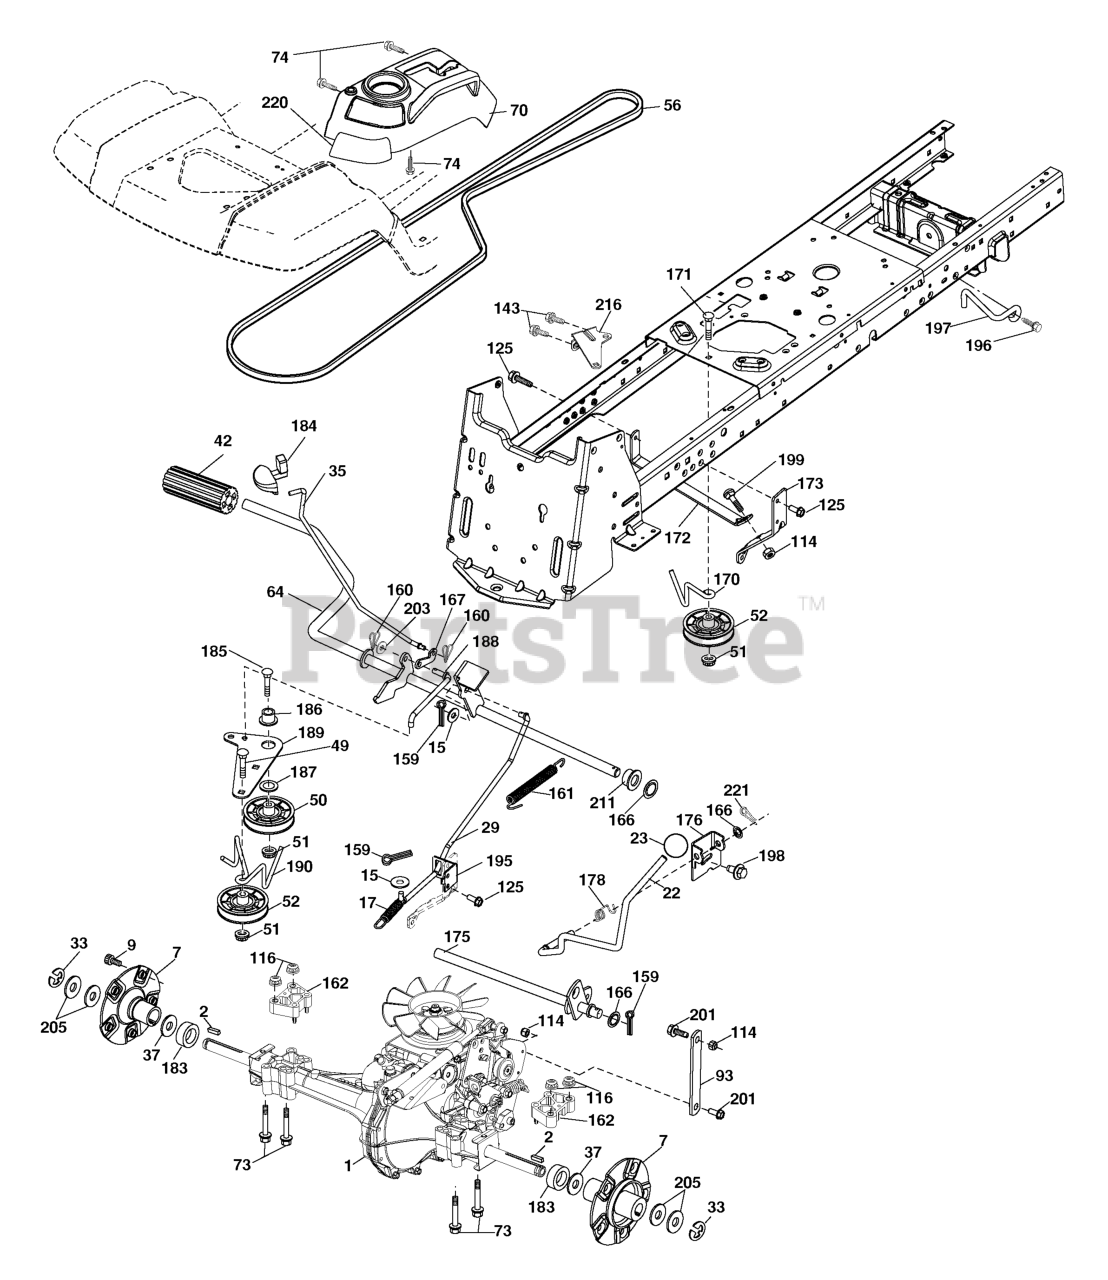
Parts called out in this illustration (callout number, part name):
2	KEY.SQUARE.187X2.500
7	HUB.ASM.WHEEL.REAR.22"
9	HUB BOLT
15	WASHER
17	SPRING.BRAKE.HG3000/3500
22	ROD.SHIFT.FENDER.STGT.
23	KNOB.DELUXE.(PISTOL.GRIP).BLAC
29	ROD.BRAKE.0610.PEDAL.CONTROL
35	ROD.BRAKE.PARKING.GT.H
42	PEDAL COVER T
50	IDLER.FLAT.910.OFFSET
51	NUT LOCK FLG 3/8-16 UNC
52	IDLER.V-GROOVE.910.OFFSET
64	SHAFT.ASM.PEDAL.BRAKE.
70	RP CONSOLE.ASM.HYDO.HUSQ.
73	BOLT.HEX.FLNG.5/16-18X3.75
74	SCREW.HI-LO.CONSOLE
93	LINK.SHIFT.T/A.0610.TE
114	NUT.71038.31-18.HEX.NYLOCK
116	NUT LOCK HEX FLANGE 5/16-18
125	SCREW
143	Screw Thdrol 5/16-18 x 1/2
159	COTTER PIN
160	RETAINER CLIP
161	SPRING.RETURN.CLUTCH.2006
162	SPACER.TRANSAXLE.18&22
166	NUT.PUSH.625.2006
167	LATCH.BRAKE.SPRING
170	KEEPER.V-IDLER.CENTER.
171	BOLT
172	STRAP.TRQ.LH.FS.HG0510
173	STRAP.TORQUE.FS.0610.RH
175	SHAFT.ASM.SHFT.HG0510/
176	ARM.CLEVIS.ROD.SHIFT
178	SPRING.SHIFT.GT2006
183	SPACER.SPLIT.800X.350
184	HANDLE.PARKG.BRK.HUSQ X667
185	BOLT
186	SPACER.RETAINER
187	WASHER 12/32X2X10GA
188	RP.LINK.CLUTCH.GROUND.DRIVE
189	BELLCRANK.GROUND.DRIVE.TEX.
190	KEEPER.BELLCRANK.DRIVE
195	BRKT.ROD.BRAKE.18/20/2
196	SCREW 3/8-16X1
197	BRKT.ANIT-ROTATION.CLUTCH
198	SCREW.7/16-14X7/8.FLAN
199	BOLT
201	BOLT SHOULDER 5/16-18 UNC
203	WASHER
211	BUSHING.SHAFT.BRAKE.HAND
216	BRACKET.PULLEY.IDLER.W/TEX
220	REFLECTOR.RH.TEX GT
221	RETAINER.SPRING.CLIP.H
